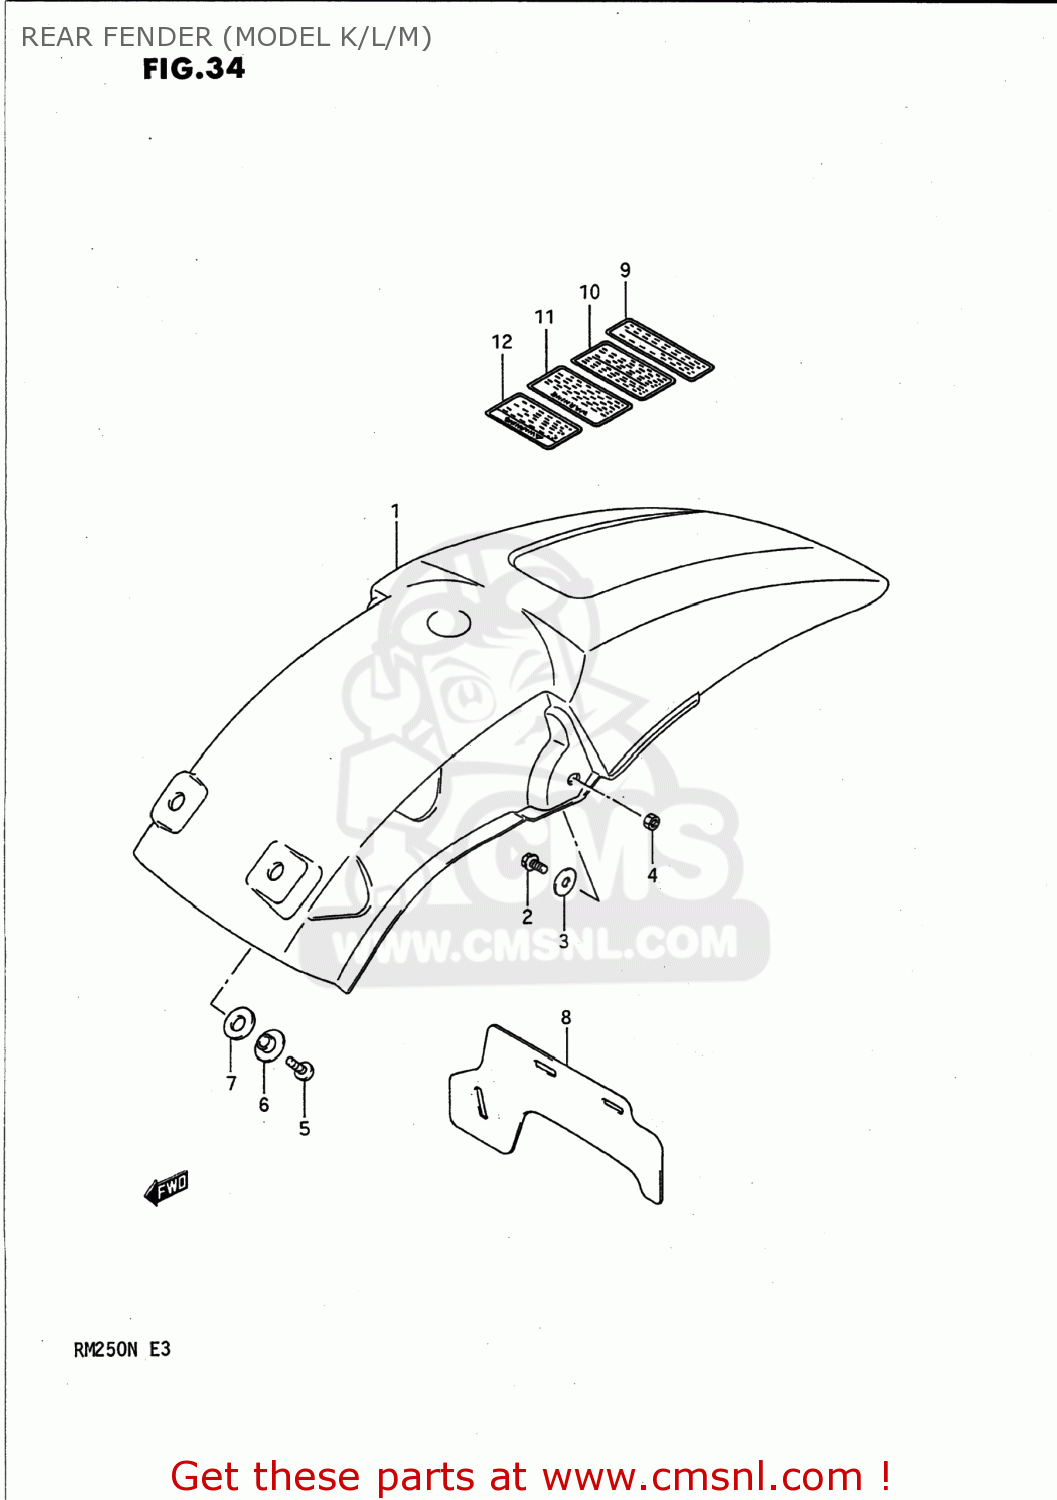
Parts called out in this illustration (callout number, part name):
1	FENDER,REAR
2	BOLT
3	WASHER (6.5X29X1.6)
4	NUT 6MM
5	SCREW
6	WASHER
7	WASHER(10.5X20X2.5)
8	MUDGUARD,RR FENDER
9	LABEL,WARNING
10	LABEL,WARNING
11	LABEL,WARNING
12	LABEL
